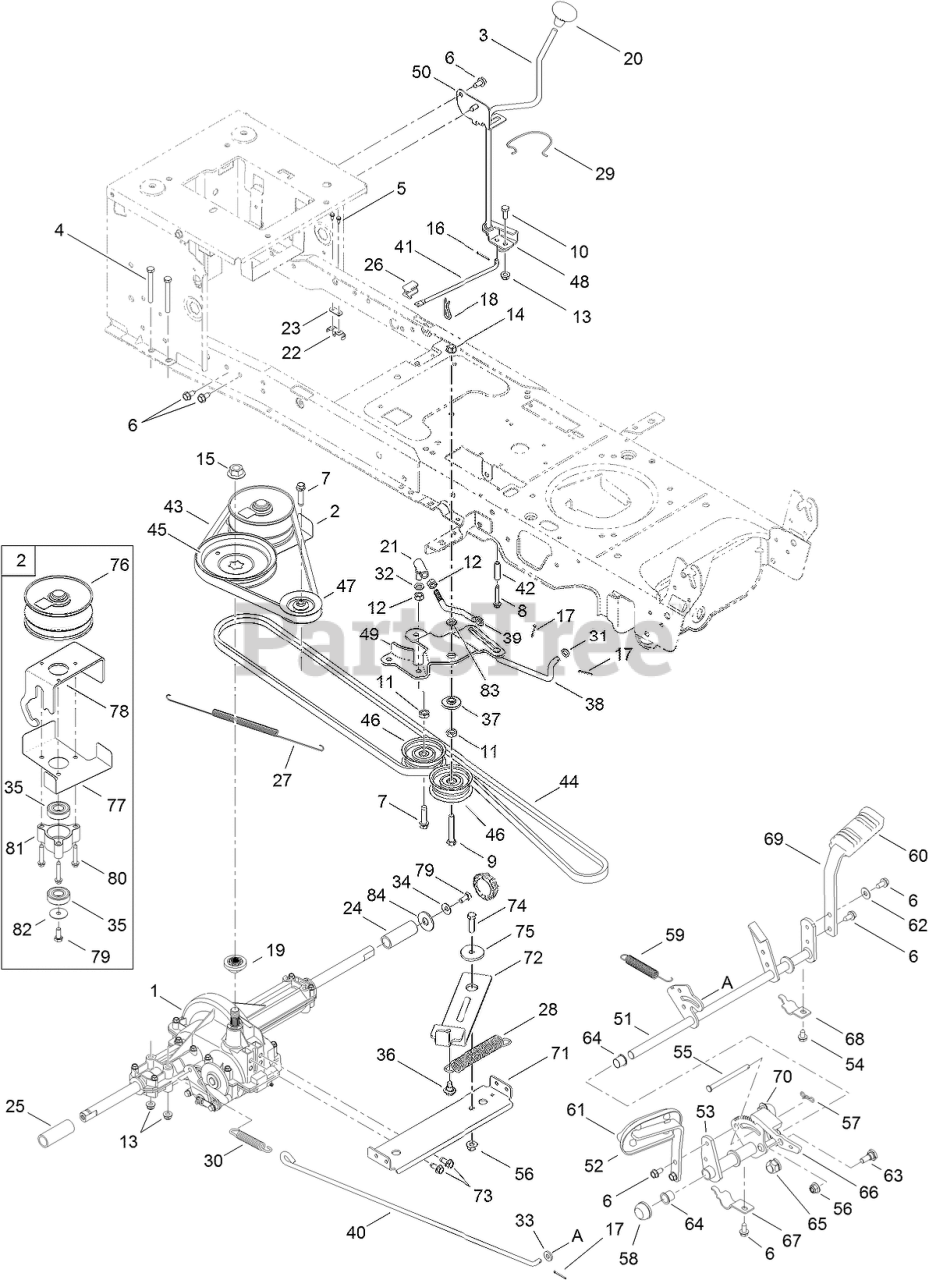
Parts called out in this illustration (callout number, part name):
1	TRANSMISSION DRIVE ASM
3	SHIFT LEVER ASM
4	SCREW-HEX
5	SCREW-HWHTF
6	SCREW-TAP
7	SCREW-TAP
8	SCREW-HH
9	SCREW-HH
11	NUT-JAM
12	NUT-HEX
13	NUT-LOCK, FLANGE
14	NUT-LOCK, FLANGE
15	NUT-FLANGE
16	PIN-COTTER
17	PIN-COTTER
18	PIN-HAIR
19	HUB-PULLEY, SPLINE
20	KNOB-SHIFT
21	BALL JOINT ASM
22	SWITCH-SPRING, SHORT
23	PLATE-INSULATOR
24	SLEEVE
25	SLEEVE
26	BEARING-PLATE, SHIFT
27	SPRING-EXTENSION
28	SPRING-EXTENSION
29	CLIP-SPRING, SHIFTER
30	SPRING-EXTENSION
31	WASHER-FLAT
32	WASHER-LOCK
33	WASHER-FLAT
34	WASHER-BELL
35	BEARING-BALL
36	BOLT-SHOULDER, TAP
37	SPACER-SHOULDER
38	ROD-BYPASS, FOOT PEDAL
39	ROD-ADJUSTMENT, IDLER
40	ROD-BRAKE
41	ROD-SHIFT
42	SPACER
43	BELT-V, POLY
44	BELT-DRIVE, VARIABLE SPEED
45	PULLEY-V (W/HUB)
46	PULLEY-IDLER, FLAT
47	PULLEY-IDLER, Y TYPE
48	BRACKET-ADJUSTMENT, SHIFT
49	BRACKET-IDLER, CENTER DOUBLE
50	BRACKET-SHIFT
51	BRAKE CONTROL ASM
52	PEDAL ASM
53	PEDAL BRACKET ASM
54	SCREW-HWH
55	PIN-CLEVIS
56	NUT-LOCK, FLANGE
57	PIN-COTTER
58	CAP-PUSH
59	SPRING-EXTENSION
60	PAD-PEDAL, BRAKE
61	PAD-PEDAL
62	WASHER-BELL
63	BOLT-SHOULDER
64	BEARING-FLANGE
65	BEARING-FLANGE, HEX (SPLIT)
66	LATCH-CRUISE
67	BRACKET-STRAP, PEDAL SUPPORT
68	BRACKET-STRAP, PEDAL SUPPORT
69	BRACKET-PEDAL, BRAKE
70	BRACKET-PLATE, REINFORCEMENT
71	BRACKET-TRANSMISSION
72	BRACKET-IDLER
73	SCREW-HWH
74	SCREW-HH
75	SPACER-SHOULDER
76	PULLEY ASM
77	BELT KEEPER ASM
78	BRACKET ASM
79	SCREW-HH
80	SCREW-HWH
81	CUP-BEARING
82	WASHER-FLAT
83	WASHER-FLAT
84	WASHER-FLAT
